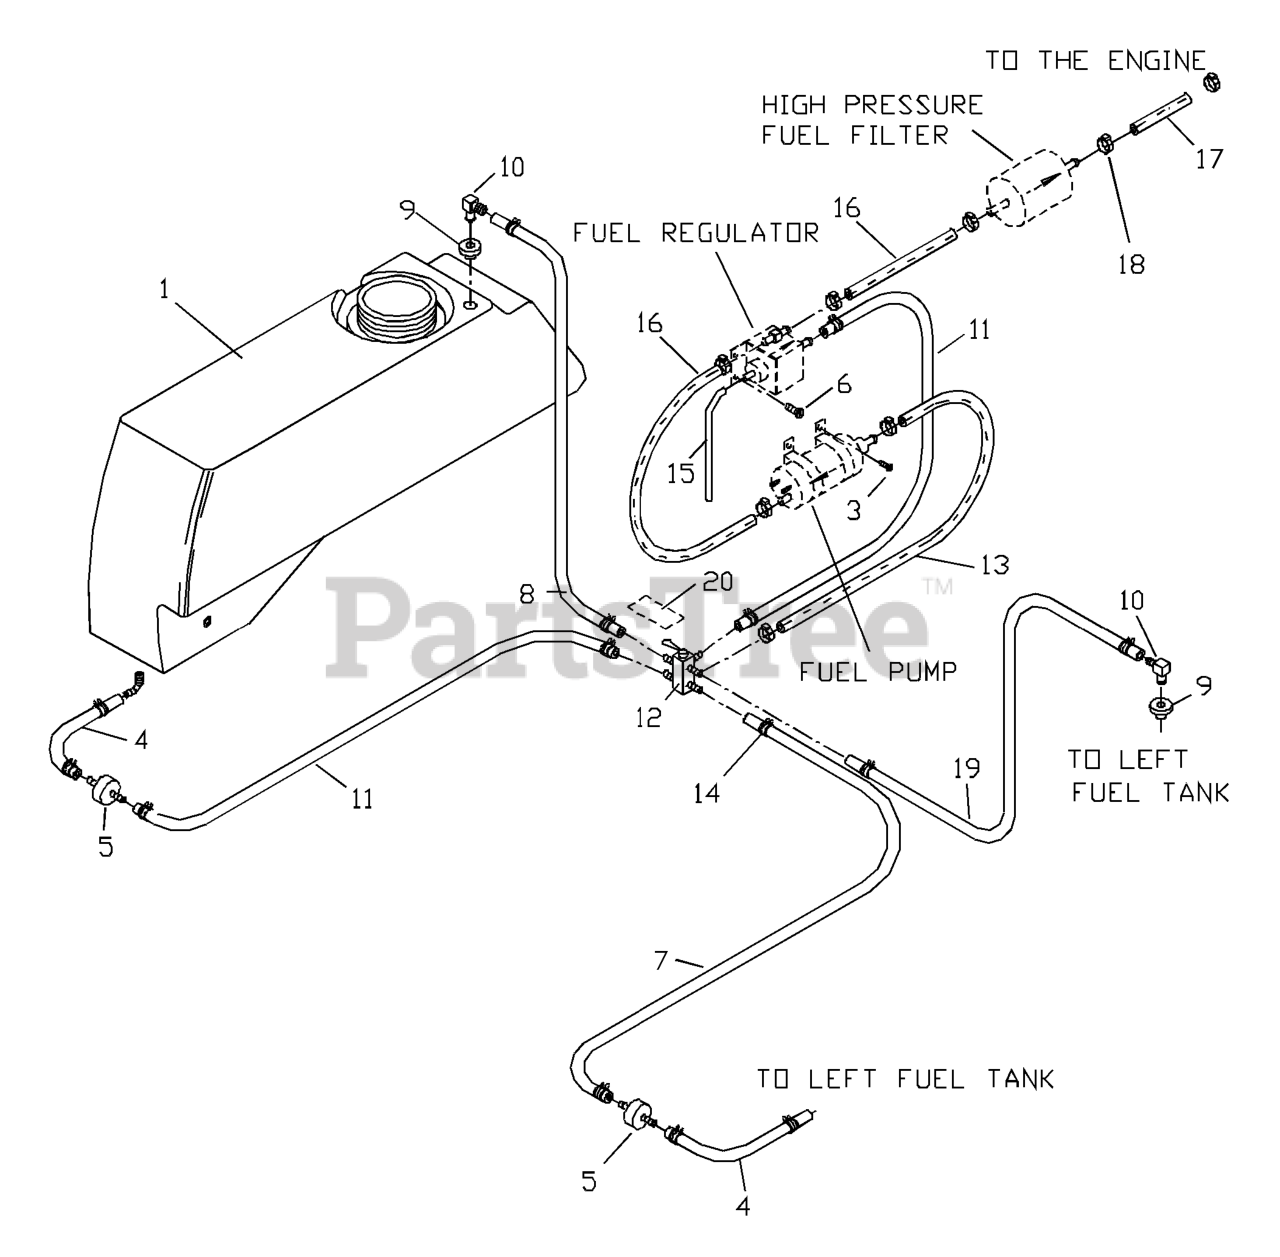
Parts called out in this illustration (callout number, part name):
1	FUEL TANK DIESEL RT
3	SCREW #10 X 1/2 SELF TAPPING
4	GAS LINE 3 1/2"
5	FUEL FILTER
6	HEX CAP SCREW 1/4
7	FUEL LINE 29.5"
8	FUEL LINE 18"
9	RUBBER GROMMET
11	FUEL LINE 24"
12	FUEL VALVE
13	EFI HOSE - 18"
14	HOSE CLAMP
16	EFI HOSE - 8"
17	EFI HOSE - 4"
19	FUEL LINE 34"
20	FUEL VALVE DECAL
